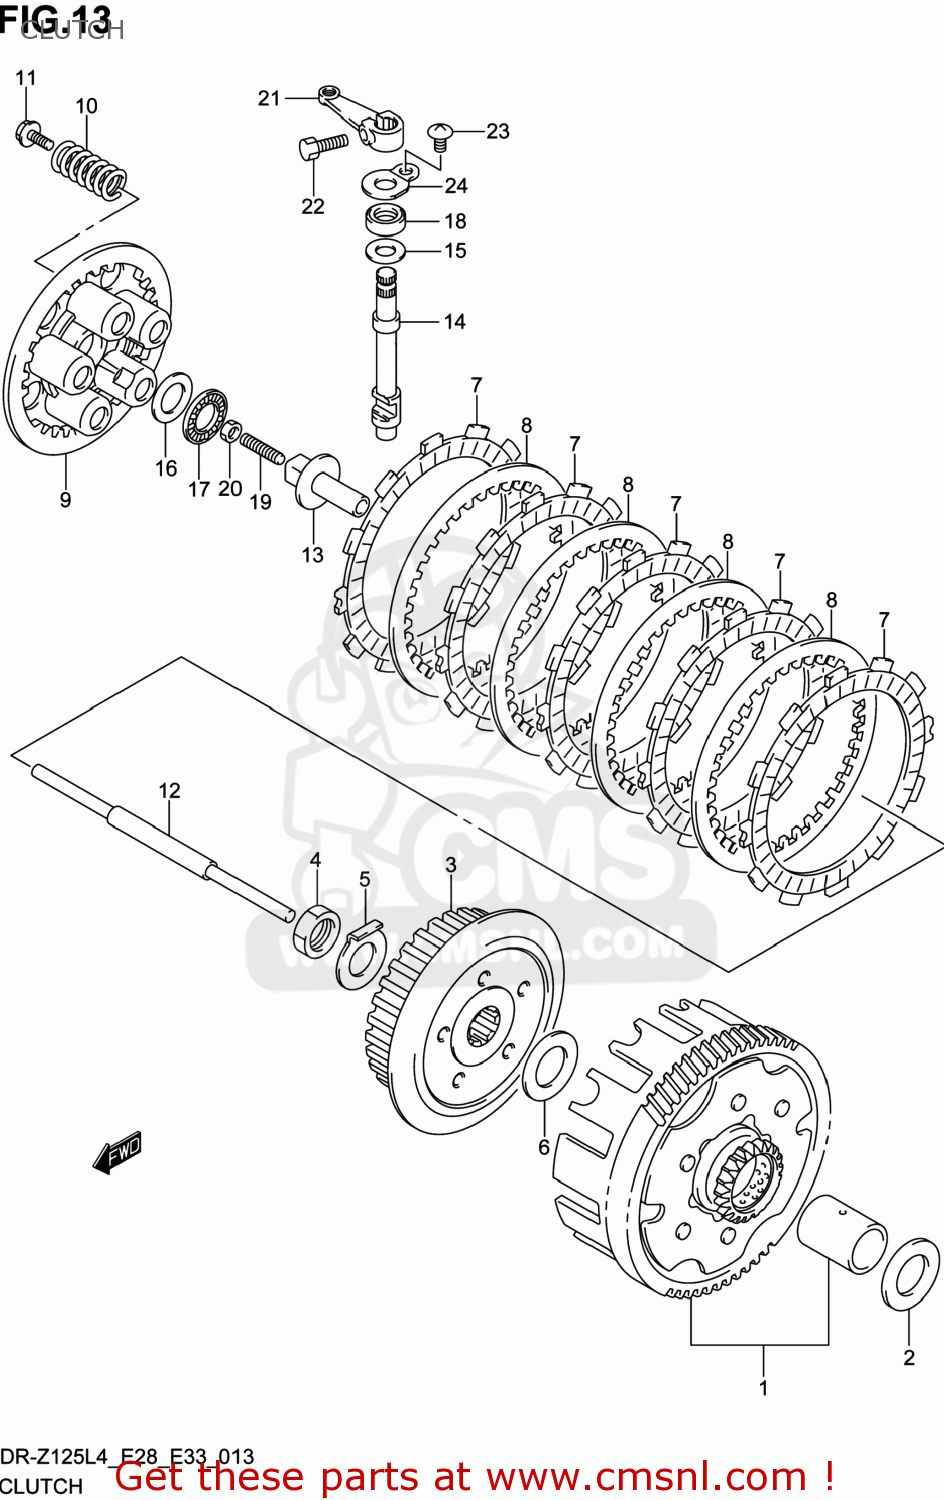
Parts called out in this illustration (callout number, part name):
1	GEAR ASSY,PRI DRIVEN(NT:59)
2	WASHER
3	HUB,CLUTCH SLEEVE
4	NUT
5	WASHER
6	WASHER
7	PLATE,CLUTCH DRIVE (NAS)
8	PLATE,CLUTCH DRIVEN (NAS)
9	DISC,CLUTCH PRESSURE
10	SPRING
11	BOLT(5X16)
12	ROD,CLUTCH PUSH
13	PIECE,CLUTCH PUSH
14	CAMSHAFT,CLUTCH RELEASE
15	SHIM(10X20X1)
16	WASHER(15.5X28X1)
17	BEARING(15X28X2)
18	SEAL,OIL(10X20X6)
19	SCREW(6X25)
20	NUT
21	ARM,CLUTCH RELEASE
22	BOLT
23	SCREW
24	RETAINER,CL RLSE OIL SEAL
